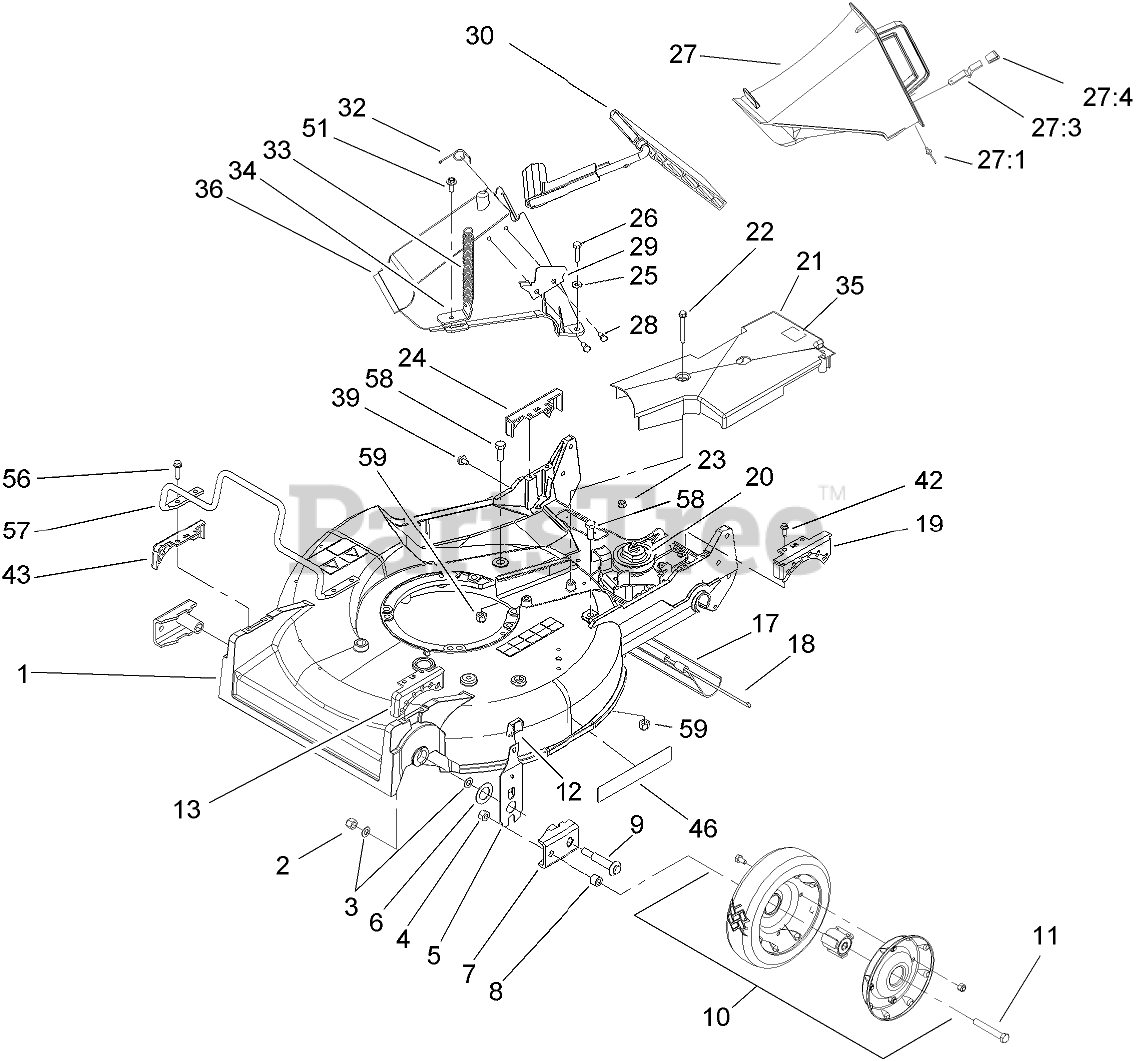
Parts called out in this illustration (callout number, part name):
1	HOUSING
2	NUT-LOCK
3	WASHER
4	NUT-LOCK, CONE
5	FRONT SPRING ARM ASM
6	WASHER-THRUST
7	ARM-PIVOT, FRONT
8	SPACER-WHEEL
9	BOLT-WHEEL
10	WHEEL AND TIRE ASM
11	SCREW-HH
12	KNOB-ARM
13	QUADRANT-FRONT, LH
17	SHIELD-TRAILING
18	ROD-SHIELD
19	QUADRANT-REAR, LH
20	GEAR CASE ASM
21	COVER-BELT
22	SCREW-HHFTF
23	NUT-LOCK, NI
24	QUADRANT-REAR, RH
25	WASHER-FLAT
26	SCREW-HH
27	DISCHARGE PLUG ASM
27:1	RIVET-HEAD, FLAT
27:3	LATCH-PLUG, DISCHARGE
27:4	GRIP-LATCH
28	SCREW-PLASTITE
29	LATCH-PLATE
30	DISCHARGE DOOR ASM
32	RETAINER-DOOR
33	SPRING-DOOR
34	BRACKET-SPRING
35	DECAL-GREASE
36	TUNNEL-DISCHARGE
39	SCREW AND WASHER ASM
42	SCREW-HWHTF
43	QUADRANT-FRONT, RH
51	SCREW-HWH
56	SCREW-HWHTF
57	GUARD-ENGINE
58	SCREW-HH
59	NUT-LOCK, NI
